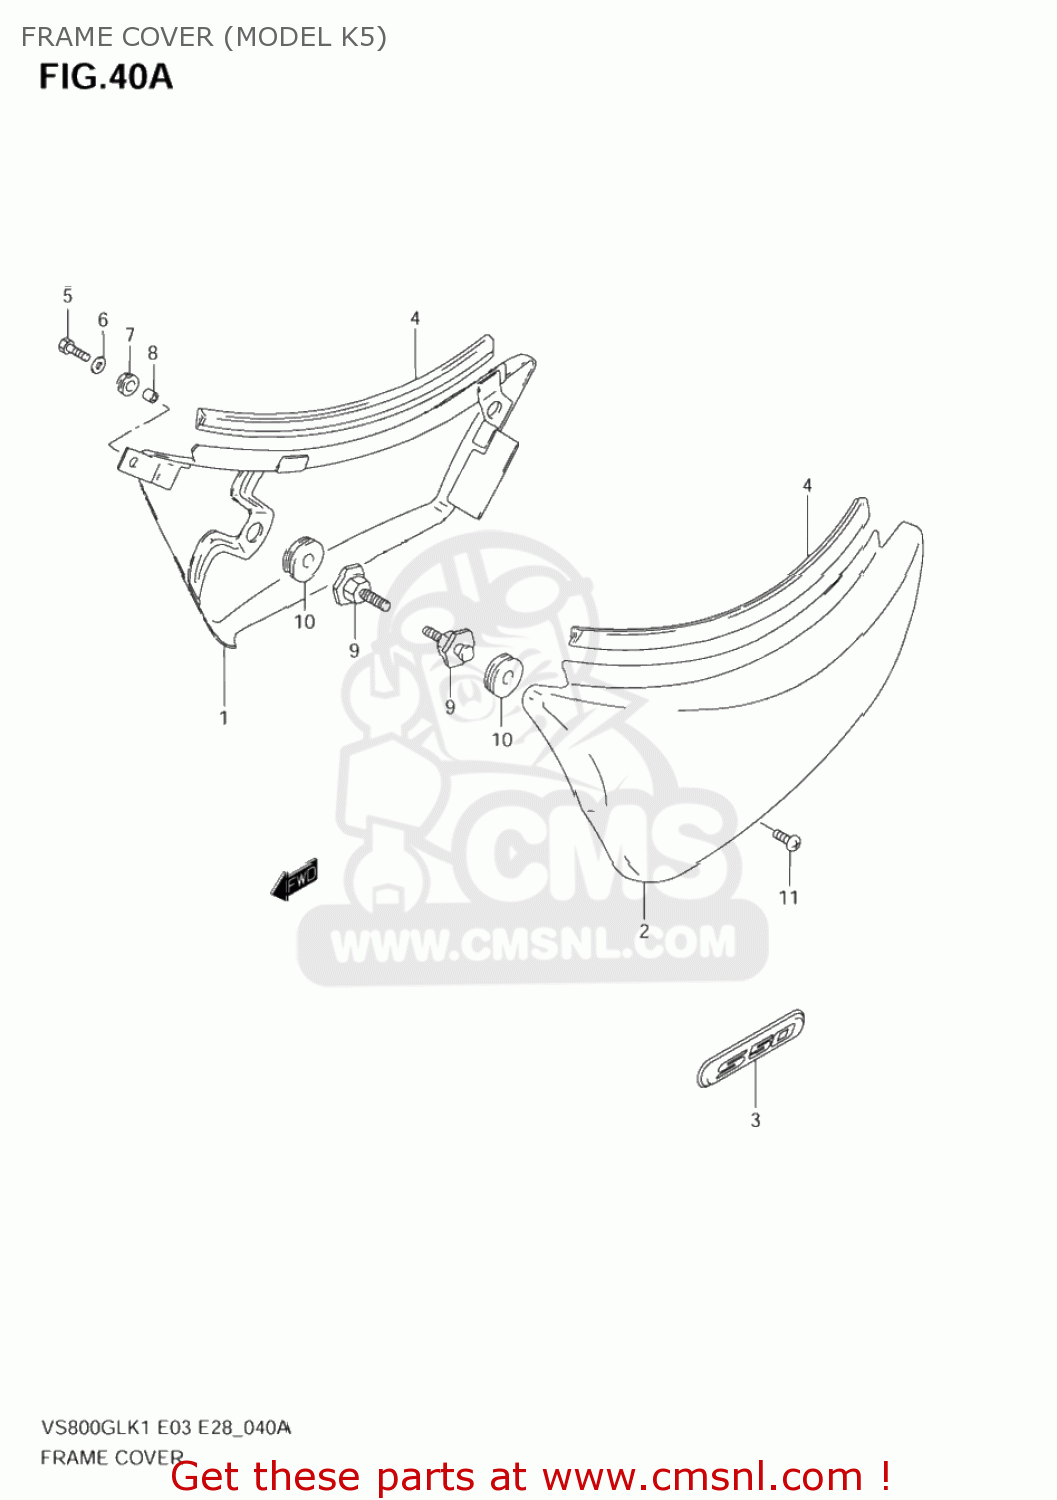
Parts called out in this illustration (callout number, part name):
1	COVER ASSY,FRAME,R(GRAY)
2	COVER ASSY,FRAME,L(GRAY)
3	EMBLEM,S50
4	MOLDING
5	BOLT
6	WASHER(6.5X18X1.6)
7	CUSHION
8	SPACER(6.1X8X5.2)
9	BOSS,FRAME COVER
10	CUSHION
11	SCREW 6X10
